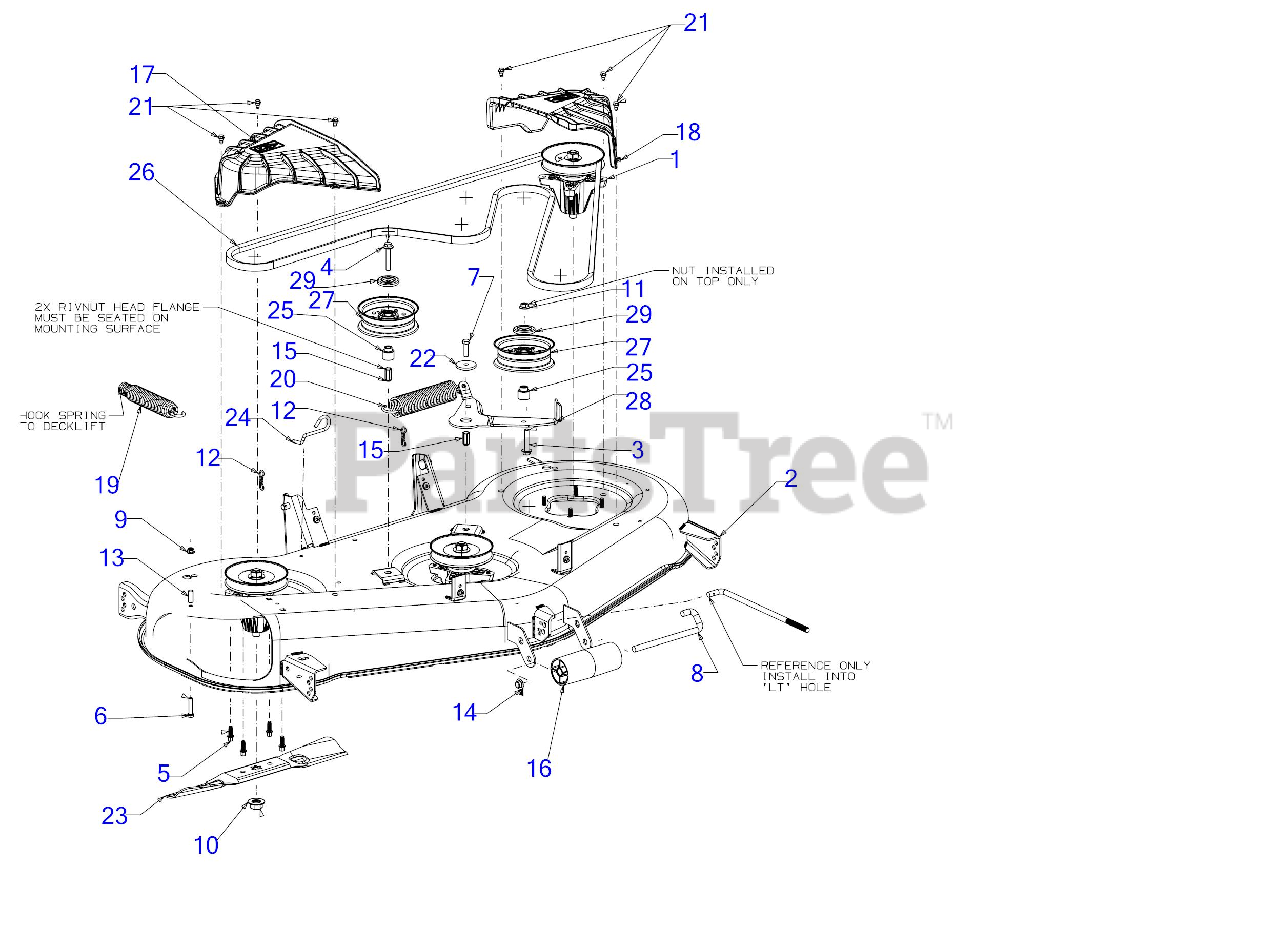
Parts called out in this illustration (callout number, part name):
1	SPINDLE ASSEMBLY
2	54" DECK SHELL
3	SCREW 3/8-16 x 2.0
4	SCREW 3/8-16 x 2.25 GR5
5	SCREW 5/16-18 X .875
6	SCREW 5/16-18 x 1.5 LG
7	SCREW 3/8-16 x 1.25 GR5
8	ROLLER PIN 1/2 x 7.31
9	FLANGE LOCK NUT 5/16-18
10	HEX NUT
11	FLANGE LOCK NUT
12	BOW TIE COTTER PIN
13	VINYL CAP
14	PUSH CAP
15	NUT RIVET 3/8-16
17	SPINDLE COVER (RH)
18	SPINDLE COVER (LH)
19	LIFT ASSIST SPRING
20	EXTENSION SPRING 1.25 OD X 8.5 LG
21	SHOULDER SCREW 1/4-20 x .50
22	SHOULDER SPACER
23	18.61" BLADE (2N1)
23	Cub Cadet 54" HI LIFT BLADE SET
23	Genuine Factory Parts 54" BLADE SET
24	DECK SPRING HOOK
25	SHOULDER SPACER
26	V-BELT B SEC x 139 LG
26	Cub Cadet 54" DECK DRIVE BELT
26	Genuine Factory Parts 54" DECK BELT
27	IDLER PULLEY 4.50" DIA
28	IDLER PIVOT BRACKET
29	IDLER PULLEY CAP
